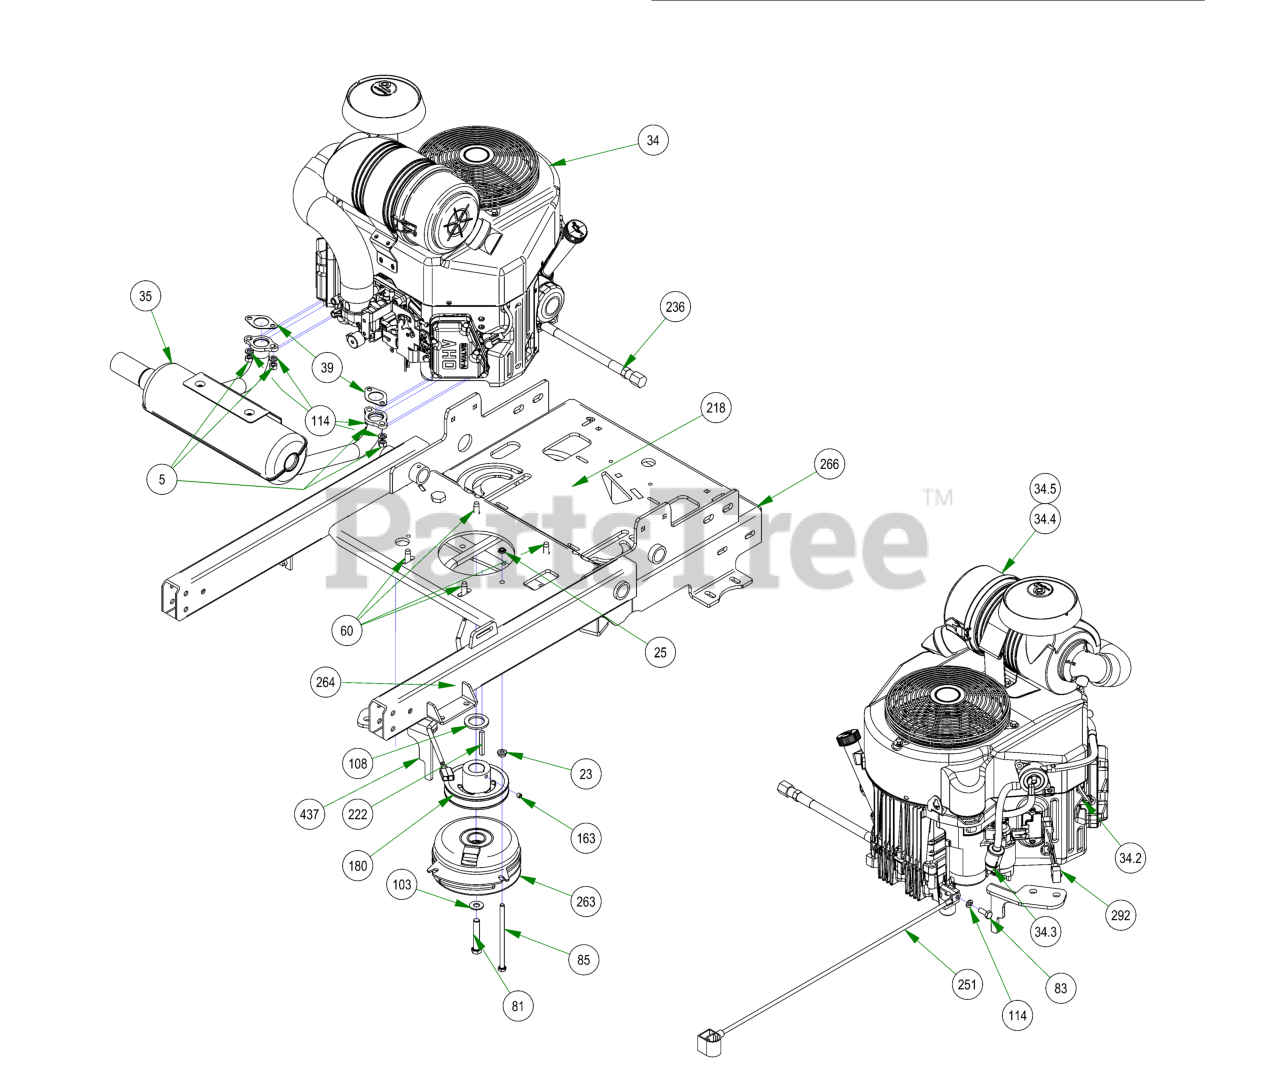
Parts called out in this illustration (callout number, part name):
5	M8-1.25 DIN 934 HEX NUT (CL.8) ZINC
23	5/16-18 HEX SERRATED FLANGE NUT HARD/ZINC
25	5/16-18 NYLON INSERT JAM LOCKNUT ZINC
34	FX691 Kawasaki-2016 Compact Outlaw
34.1	Exhaust Gasket
34.2	Spark Plug - Kawasaki
34.3	Universal Inline Fuel Filter
34.4	Canister Air Filter- Outer
34.5	Canister Air Filter- Inner
34.6	Oil Filter
35	Exhaust-Stand On-FX691V Kawasaki
39	Exhaust Gasket
60	3/8-16 X 1-1/8HEX WASHER UNSLOT SERRATED (TRI-LOB) TRS
81	7/16-20 X 2-1/2 HEX CAP SCREW (GR.8) ZINC YELLOW
83	M8-1.25 X 20MM DIN 933 HEX TAP BOLT (CL 8.8) ZINC
85	5/16-18 X 5-1/2 HEX CAP SCREW (GR.5) ZINC
103	3/8 FLAT WASHER USS (1" OD) ZINC
108	1.140 ID X 1.750 OD X .132 THICK FLAT WASHER PLAIN
114	5/16 SPLIT LOCKWASHER ZINC
163	5/16-24 X 1/4 SOCKET SET SCREW (CUP PT) PLAIN
180	4 3/4 Motor Pulley
218	2019 Renegade Pump Belt
222	1/4 X 2 SQ MACHINERY KEY 1018 STL PLAIN
236	Oil drain Hose
251	24 inch Black Cable – MZ/ZT
263	Clutch Assembly
264	Clutch Pigtail
266	2020 36" Stand On Frame
292	2019 Harness Adaptor-Gen2 FX-ALL
437	2019 Stand On Clutch Stop Bracket
